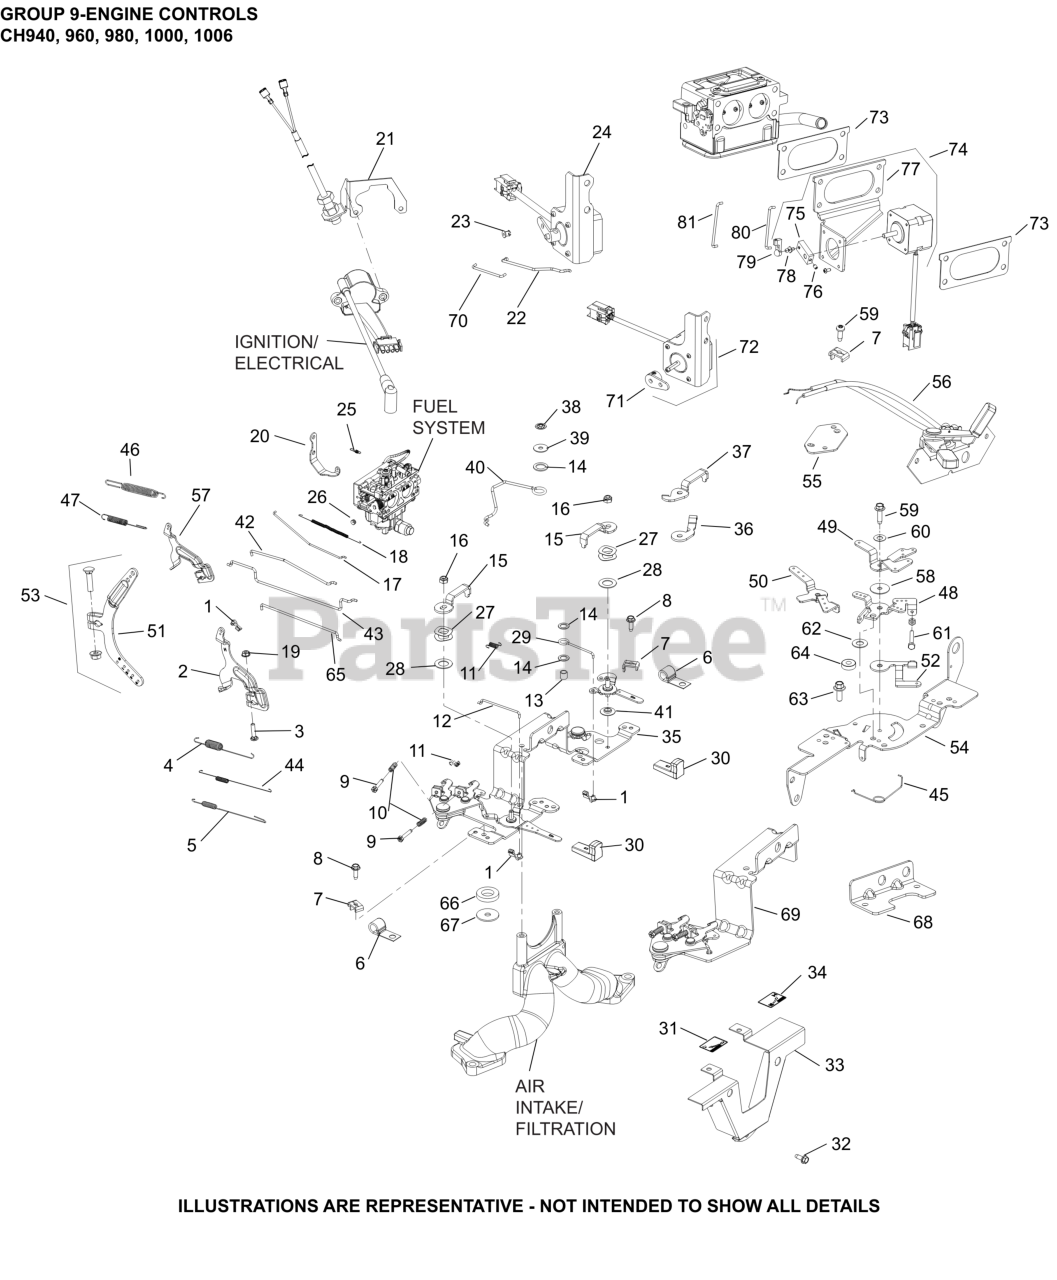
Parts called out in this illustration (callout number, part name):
76	SCREW, SET #6-32
77	BRACKET, STEPPER MOTOR
78	SCREW, CUP JOINT GOVERNOR
79	CUP, BALL JOINT
81	LINKAGE, THROTTLE
NI	LEVER, STEPPER MOTOR
NI	ROTARY, STEPPER MOTOR ASSEMBLY
